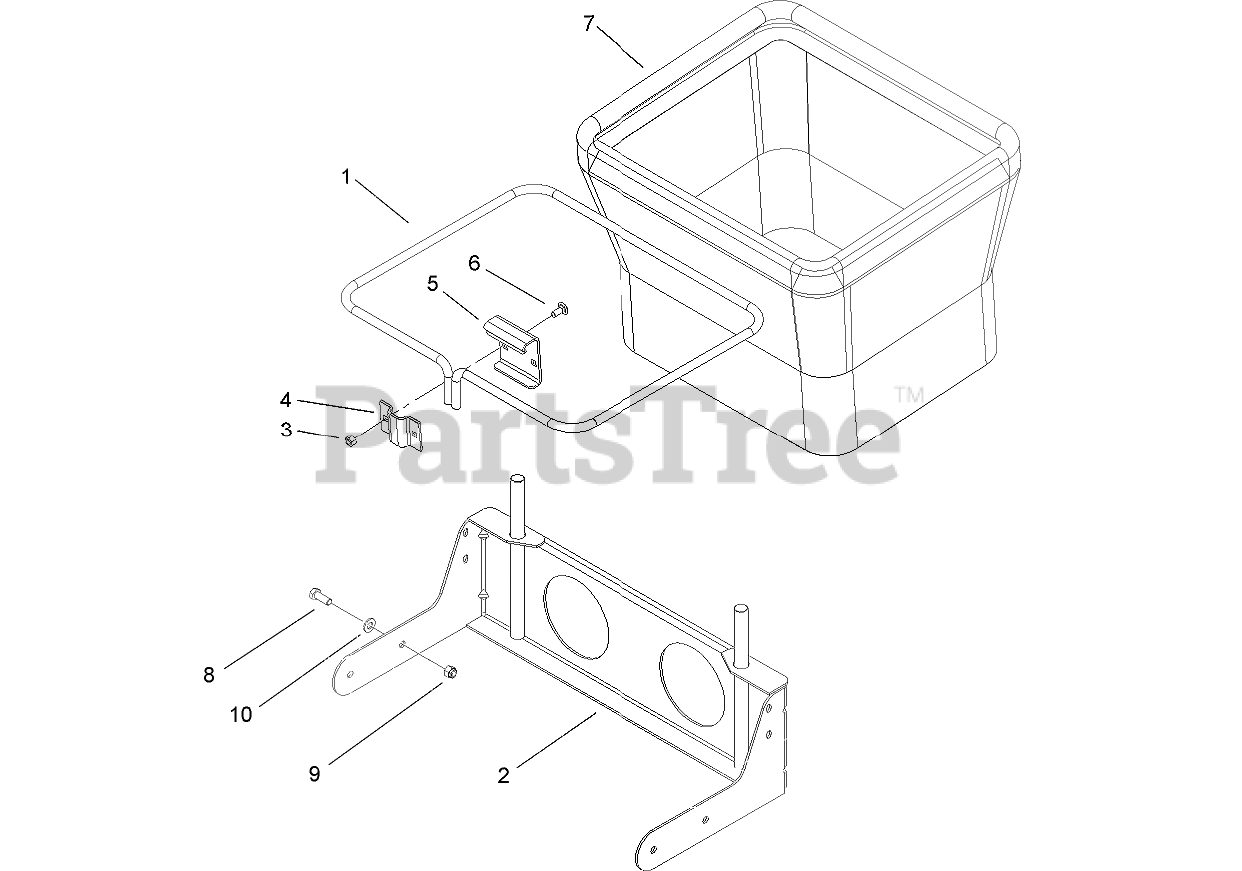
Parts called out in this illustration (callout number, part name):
1	FRAME-BAG
2	BAGGER SUPPORT ASM
3	NUT-LOCK, NI
5	HANGER-BAG
6	BOLT-CARR
8	SCREW-HH
9	NUT-LOCK, NI
10	WASHER-FLAT
